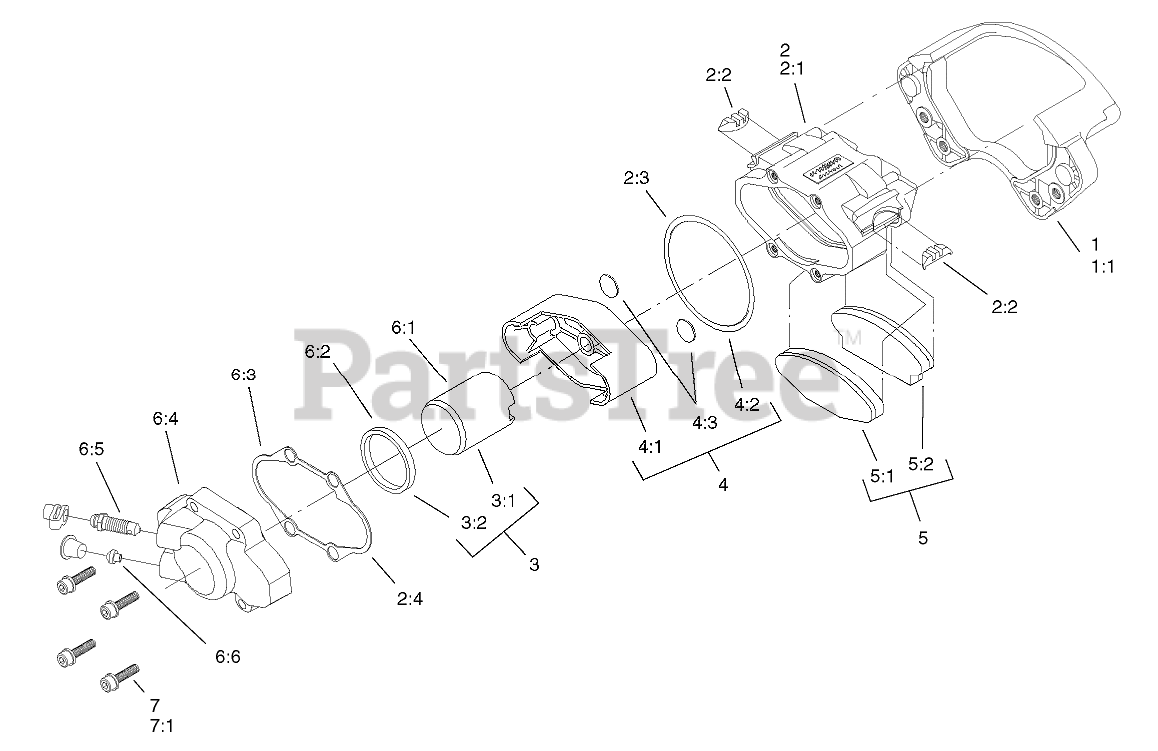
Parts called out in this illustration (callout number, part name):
1	BRACKET KIT
1:1	Bracket
2	HOUSING KIT
2:1	Housing
2:2	Spring-Rubber
2:3	Seal-Dust
2:4	Gasket
3	PISTON & SEAL KIT
3:1	Piston-Round
3:2	Seal-Square
4	PISTON & O-RING KIT
4:1	Piston-Oval
4:2	Seal-Dust
4:3	Plug-Piston
5	PAD KIT
5:1	Pad/Holder ASM
5:2	Pad/Holder ASM
6	RH PISTON & COVER ASM KIT
6:1	Piston-Round
6:2	Seal-Square
6:3	Gasket
6:4	Cover
6:5	Screw-Bleeder
6:6	Insert-Seat
7	BOLT KIT
7:1	Screw-Cover
